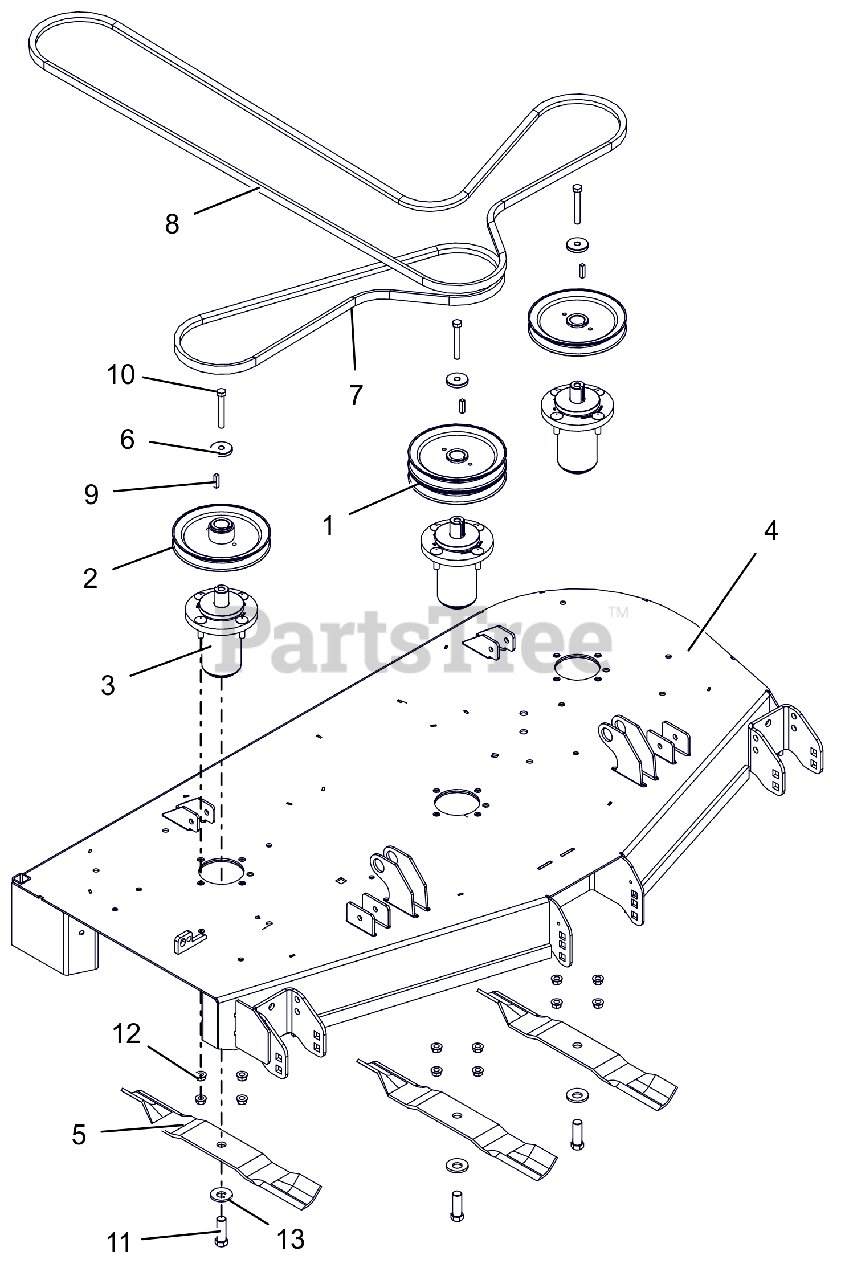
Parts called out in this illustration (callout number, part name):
1	PULLEY, DOUBLE-1"ID X 6.75"OD
2	PULLEY, V-1" ID X 6.75" OD
3	ASM, MAINT FREE ALUM SPINDLE
4	KIT,DECK-52" W/DECALS-GRAVELY
5	BLADE, 18"
6	RETAINER, SHEAVE
7	V-BELT, B-COGGED
8	V-BELT, HB SECTION
9	KEY, SQ .25X.25X1.00 RC 40-50
10	BLT, HEX .38-16X2.75 G8 ZCC
11	BLT, HEX .62-18X1.75 G8 ZCC
12	NUT-LK-CTR-FLG .375-16 GF ZCC
13	WSHR-BLVL .669X1.535X.138
